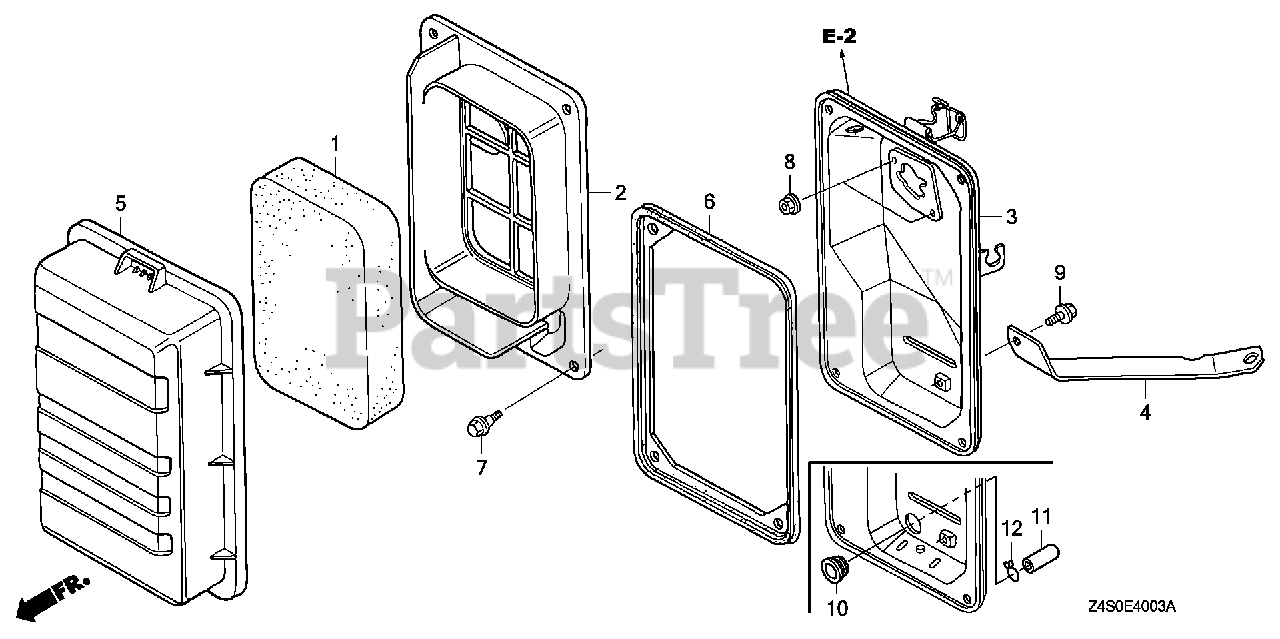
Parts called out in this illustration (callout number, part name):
1	ELEMENT, AIR CLEANER
2	SEPARATOR, AIR CLEANER
3	HOUSING, AIR CLEANER
4	STAY, AIR CLEANER
5	COVER, AIR CLEANER
6	SEAL, AIR CLEANER
7	BOLT, TURN SIGNAL SETTING
8	NUT, FLANGE (6MM)
9	BOLT, FLANGE (6X10)
10	GROMMET, AIR CLEANER
11	CAP, SEALING
12	CLIP, TUBE (B10)
